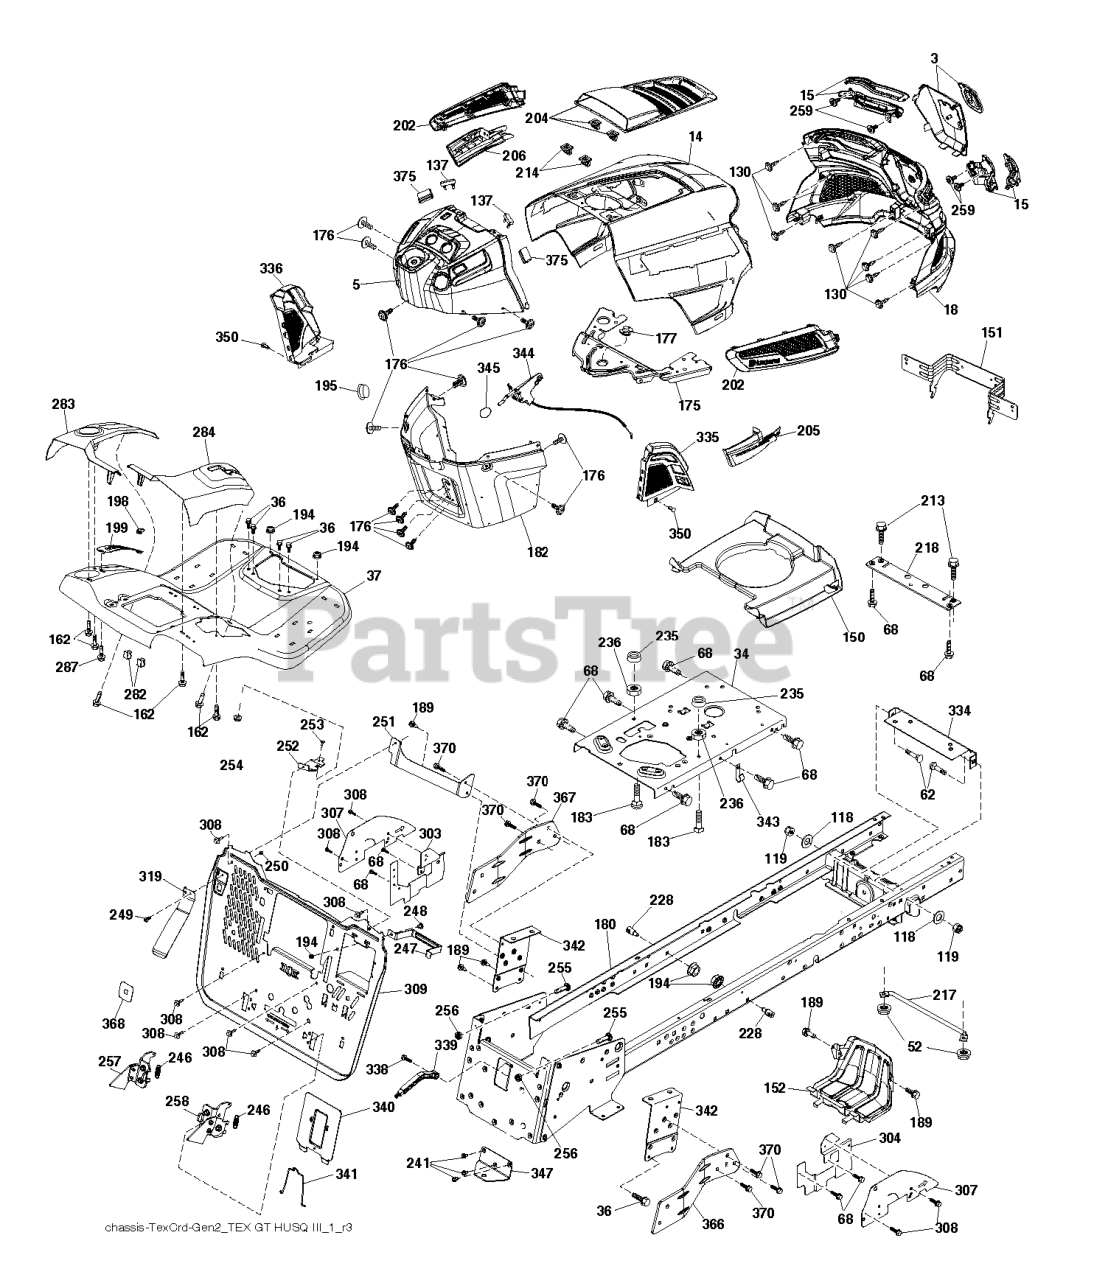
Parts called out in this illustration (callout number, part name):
14	HOOD.ASM.HUSQVARNA.GT.TEX.ORAN
15	Service Kit
36	SCREW 5/16"
37	FENDER.TEX.SRD.CRD.FRN.GUARDS
118	WASHER PLAIN WASHER 3/8 X 0.08
137	BUMPER DASH
150	AIR.DUCT.GTV.BLACK
151	BRACKET.PIVOT.HOOD.GT.HUSQ.II
152	SHIELD.BROWNING.PNT.GT.V2
175	PLATE.PNT.CROSSMEMBER.HUSQ/PRE
176	SCREW.#10-24X5/8.RN.QU
177	BUSHING STEERING
180	CHASSIS WELDMENT.CRD2.BKP_BLTS
182	DASH.LOWER.HUSQPREDGT.-CR.+EZM
189	SCREW
195	PLUG.HOLE.DASH.LOWER.12V.BLK
198	INDICATOR.DECK.LIFT.RED
199	PLATE DECK LIFT
205	SIDE.TRIM.RH.GT.HUSQ.II
206	SIDE.TRIM.LH.GT.HUSQ.II.GRAY
213	SCREW HEXAGON HEAD SCREW 5/16-
214	CLIP.RETAINER.TINNER.
217	ROD.PIVOT.HOOD
218	X-PIECE.HOOD.STOP.NON/
228	STUD.W/"D"ANTI-ROTATION
236	NUT.CENTERLOCK.5/16-
246	SPRING.LTCH.BGR.GEN2.5.CRD.TEX
247	STRAP.BATTERY.TCRD.GEN2.5X431
248	BOLT.CARR.5/16-18X1/2
249	SCREW.BUTTONHD.10-24X1/2.(2 2)
251	BRACKET.PNT.LH.SUPP.BKPLT.EDIP
252	BRACKET.PNT.RH.SUPP.BKPLT.EDIP
253	BOLT CUP HEAD SQUARE NECK BOLT
254	NUT T
257	LATCH.ASM.BGR.LH.GEN2.5.STMPD
258	LATCH.ASM.BGR.RH.GEN2.5.STMPD
282	CLIP.RETAINER.CONSOLE.LT.HUSQ
283	CONSOLE.DECKLIFT.CRDII.498
284	CONSOLE.PEDAL.HYDRO
287	SCREW 1/4X20
303	SHIELD.LWR.LH.30DECK/CRD1&2
304	SHIELD.LWR.RH.30DECK/CRD2PEDAL
307	SHIELD.UPPER.CRD.SRD.ISO
308	BOLT.5/16-18UNCX3/4 W/SEMS.BLK
309	BACKPLATE.TEXCRD2.5.BAGGER.479
319	LEVER.PRSNC.BGR.TEX.CRD.GEN2.1
334	BRACKET.ENGINE
335	COVER.LOWER.DASH.RH.BLACK
336	COVER-LH.LOWER.DASH.GT2.BLACK
339	LEVER LEVER BAGGER
340	BATTERY.DOOR.TCRD.GEN2.5.MS479
341	LATCH.BATTERY.DOOR.TCRD
342	SUPPORT.PNT.FENDER.CRD.TEX
343	CLIP CLIP
344	CONTROL.EZ.MULCH.TEX/CRD
345	RP KNOB.OVAL.TAPERED.3/8-16BLK
347	HITCH HITCH TOW TEX CRD GEN 2
350	CLIP.X-MAS.TREE
367	Brackets
368	FULL.LEVER.BAGGER.TEX.CRD
370	SCREW 3/8-16X1
375	BUMPER CLIP-ON. DASH 1"
